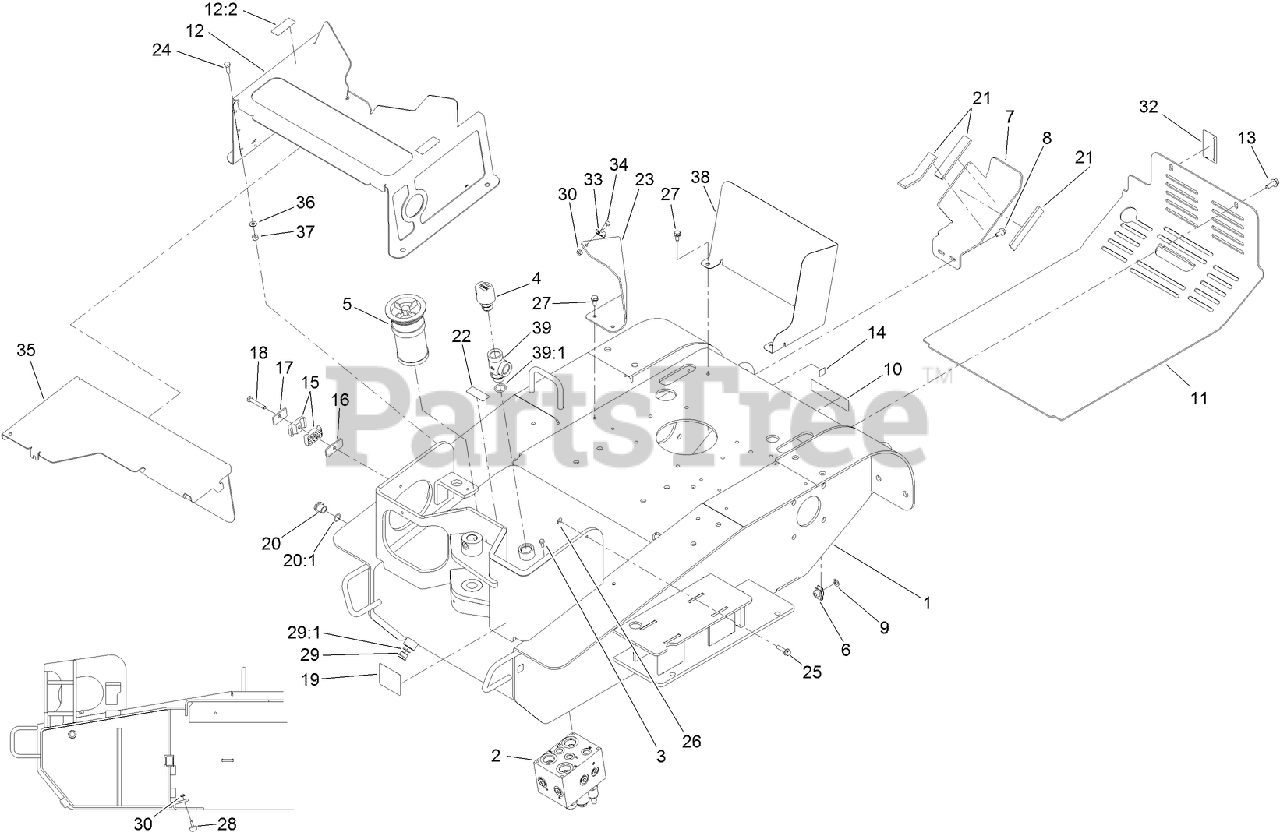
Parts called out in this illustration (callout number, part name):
1	FRAME-MAIN
2	VALVE-CUTTER
3	SCREW-HH
4	BREATHER
5	CARTRIDGE-FILTER
6	Nut-Tinnerman
7	BRACKET-TANK
8	SCREW-HHF
9	NUT-PUSH
10	DECAL-DANGER
11	COVER-REAR
12	MUFFLER COVER ASM
12:2	DECAL-SURFACE, HOT
13	SCREW-HHF
14	DECAL-POINT, LIFT
15	CLAMP-TUBE
16	PLATE-CLAMP
17	COVERPLATE
18	SCREW-HH
19	DECAL-WARNING
20	SIGHT GLASS ASM
20:1	O-RING
21	PAD-FOAM
22	DECAL-OIL, HYD
23	PLATE-DFLECTOR,RH
24	SCREW-HH
25	SCREW-HHF
26	NUT-PUSH
27	SCREW-HWHTF
28	BUMPER
29	PLUG-HEX
29:1	O-RING
30	NUT-HF
32	DECAL-BRAKE, PARKING
33	CLIP-CLOSED, INSULATED
34	SCREW-HH
35	COVER-FRONT
36	WASHER-PLAIN
37	NUT-LOCK, NI
38	BRACKET-DEFLECTOR
39	FITTING-TEE
39:1	O-RING
